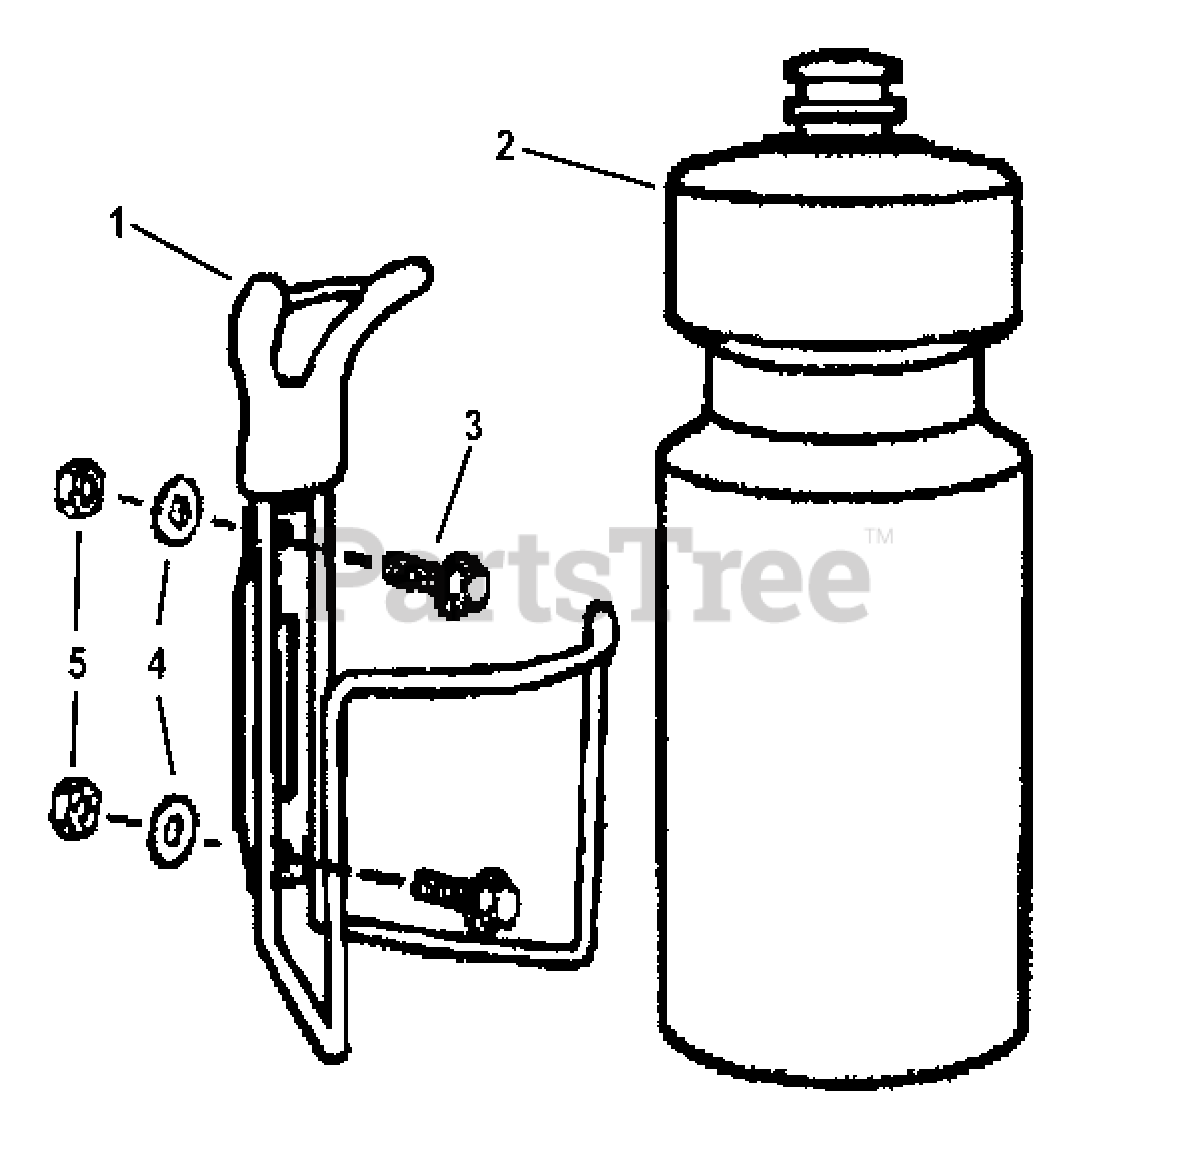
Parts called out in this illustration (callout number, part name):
1	HOLDER, Wire Bottle
2	BOTTLE, Water
3	SCREW, 10C 518" Hex Washer ST
4	WASHER, #10 Flat
5	NUT, 10-24 Nyloc
